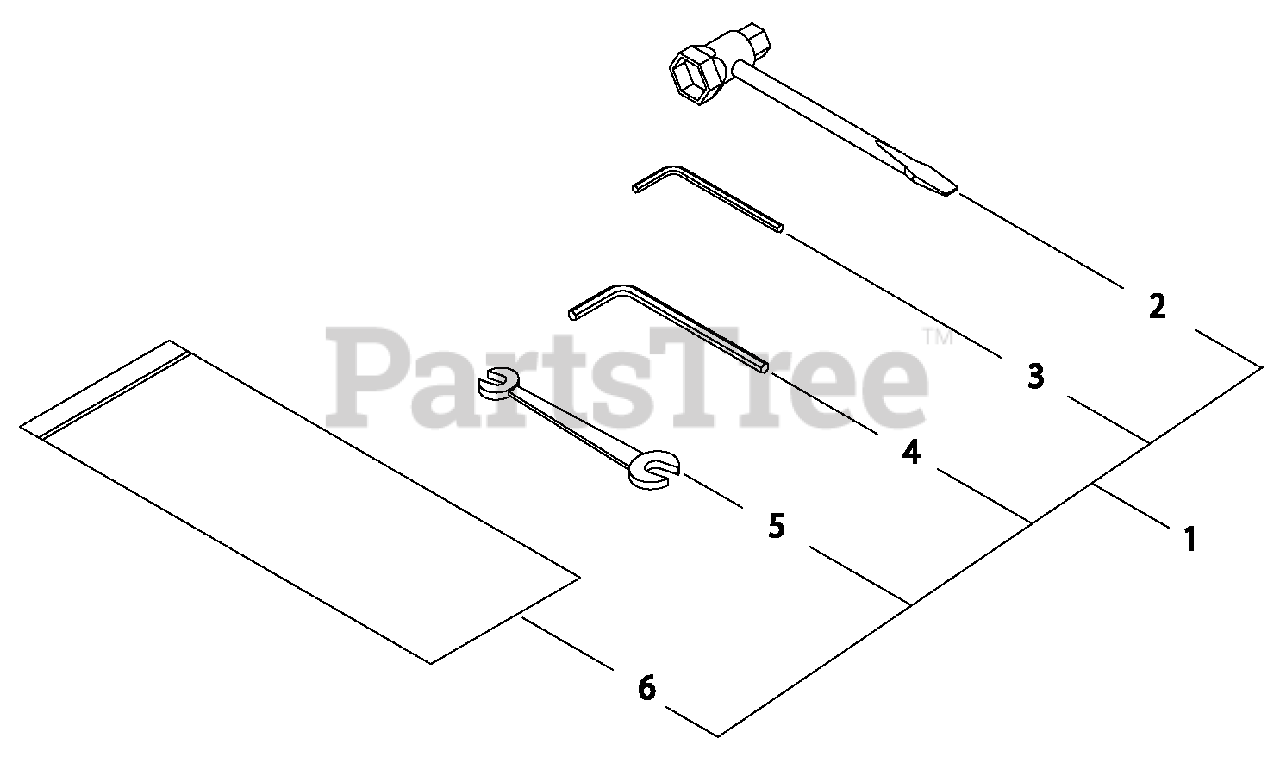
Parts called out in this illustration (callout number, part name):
1	TOOL KIT
2	T-WRENCH - 17X19mm
3	HEX KEY - 4mm
4	HEX KEY - 6mm
5	SPANNER - 8X10mm
6	BAG, TOOL
